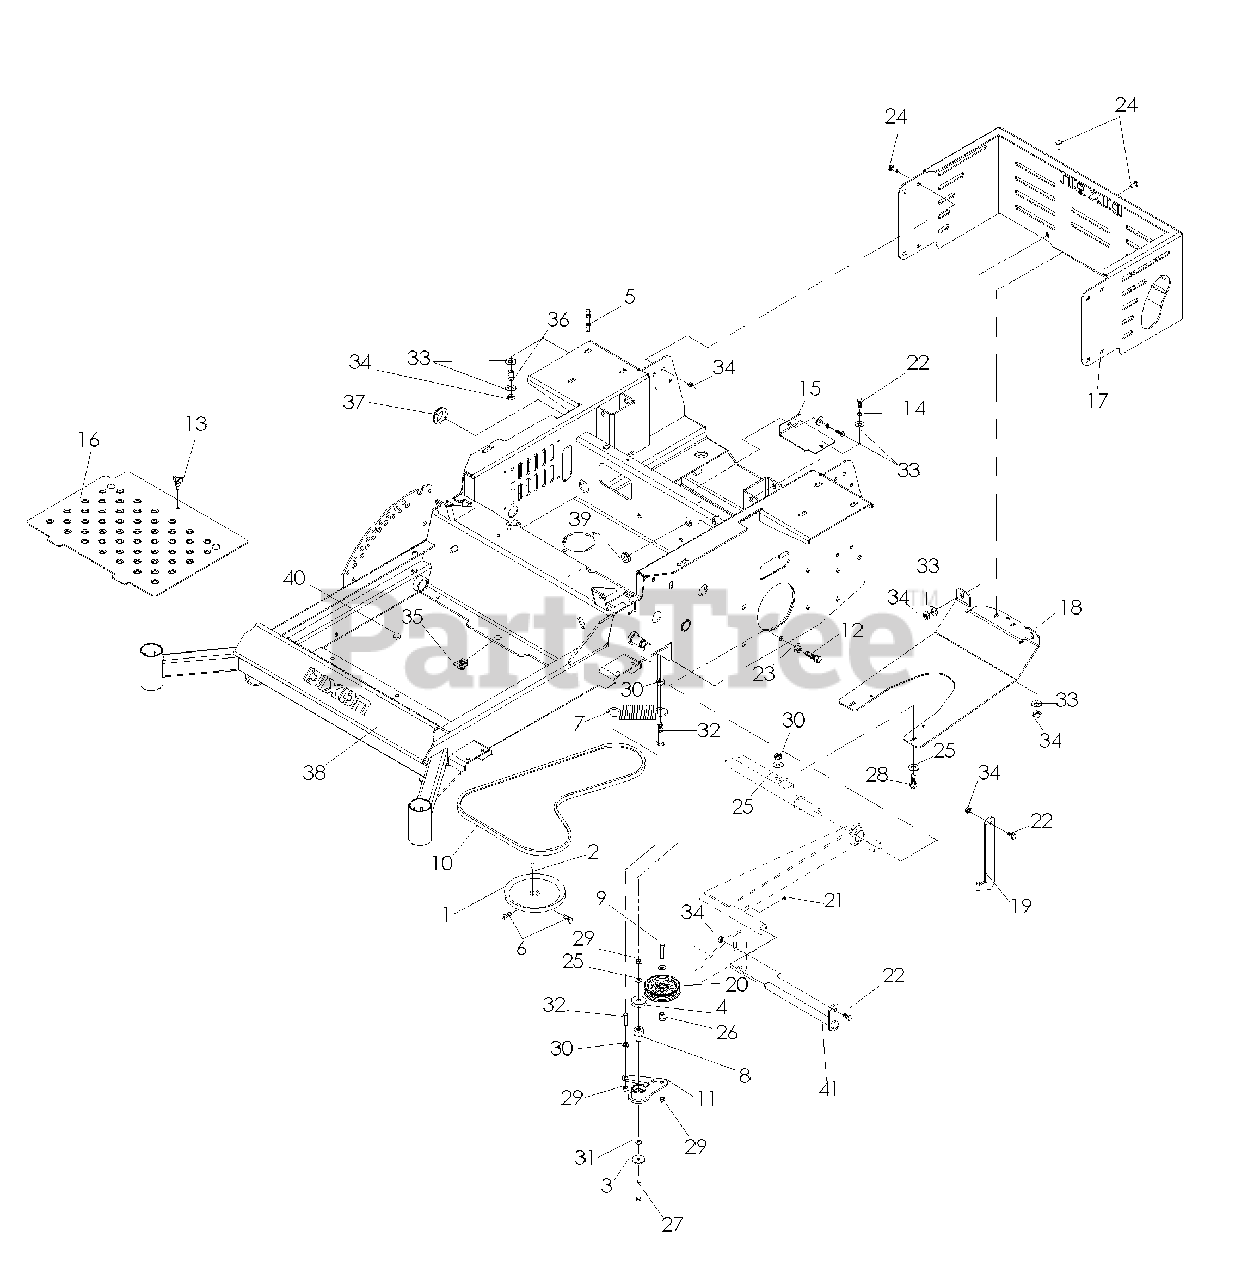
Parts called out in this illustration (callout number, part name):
2	KEY 5 MM SQ X 25 MM
3	WASHER, 3/8 SPEC
4	SHIELD, DUST
5	STUD, 5/16C
6	SCREW 5/16C X 5/8 SQ HEAD
8	PIVOT, BEARING
9	HCS 3/8C X 2
10	PUMP BELT
11	ARM, IDLER - W/BEARINGS
12	HEX SCREW 7/16-14 X 1 GR8
13	KNOB W/STUD
14	WASHER 5/16 LOCK
15	IDLER COVER
16	FLOOR PLT W/DECAL
17	GRD, REAR W/DECAL
18	PLATE, SKID
19	STOP, SEAT
20	IDLER PULLEY
21	ZERK
22	HCS 5/16C X 1
23	WASHER 7/16 LOCK
24	BOLT 5/16C X 3/4" CARRIAGE
25	WASHER 3/8 FLAT
26	BUSHING, IDLER FLANGE
27	HEX SCREW 3/8-20 X 2.75
28	HCS 3/8C X 1
29	NUT 3/8-16 NYLOC
30	NUT 3/8C WHIZ
31	WASHER 3/8 SAE FLAT
32	HCS 3/8C X 1 1/2
33	WASHER 5/16 FLAT
34	NUT 5/16 NYLOC
35	U-CLIP 5/16-18 NUT RETAINER
37	GROMMET
38	FRAME W/DECALS
38	FRAME 72" W/DECALS
39	GROMMET, FUEL LINE
40	GROMMET, BUMPER
